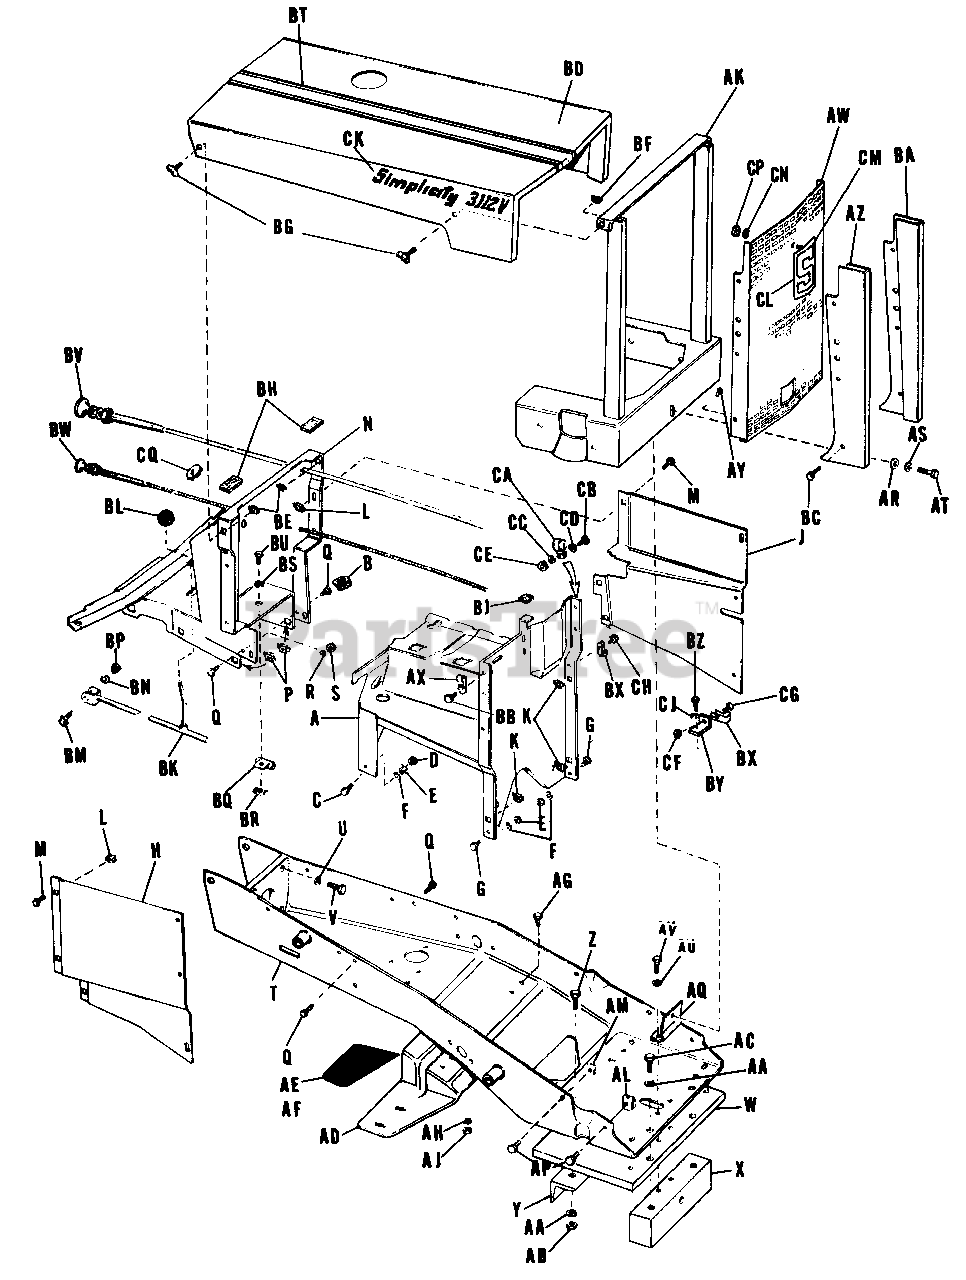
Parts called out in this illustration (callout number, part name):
A	Support Assembly, Fuel Tank & Battery
B	Steering Bushing
C	Hex. Cap Screw, 5/16"-18 x 1-1/4"
D	Full Lock Hex. Nut, 5/16"-18
E	Full Hex. Nut, 5/16"-18
F	Lock Washer, 5/16"
G	Hex. Cap Screw, 5/16"-18 x 5/8"
H	R.H. Side Panel
J	L.H. Side Panel
K	Nut Retainer
L	Nut Retainer
M	Hex. Cap Screw, 1/4"-20 x 5/8"
N	Inst. Panel Assembly
P	Nut Retainer (Frame Cover)
Q	Hex. Cap Serew, 1/4"-20 x 5/8"
R	Lock Washer, 1/4"
S	Full Hex. Nut, 1/4"-20
T	Frame Assembly
U	Lock Washer, 7/16"
V	Hex. Cap Screw, 7/16"-14 x 1-1/2"
W	Base Weight
X	Front Support, 1-3/4" x 2-1/2" x 8-5/8"
Y	Angle Assembly (Frame Rear)
Z	Hex. Cap Screw, 7/16"-14 x 1-1/2"
AA	Lock Washer, 7/16"
AB	Full Hex. Nut. 7/16"-14
AC	Hex. Cap Screw, 7/16"-20 x 1-1/2"
AD	Foot Rest
AE	L.H. Foot Rest Pad
AF	R.H. Foot Rest Pad
AG	Hex. Cap Screw 3/8"-16 x 3/4"
AH	Lock Washer, 3/8"
AJ	Full Hex. Nut 3/8"-16
AK	Cover & Tube Assembly
AL	Retainer Nut, (Front)
AM	Retainer Nut, (Rear)
AP	Hex Screw, Whiz-Lock Flange, 5/16-18 x 3/4
AQ	Bracket Assembly
AR	Plain Washer, 5/16"
AS	Lock Washer, 5/16"
AT	Hex. Cap Screw 5/16"-18 x 1-1/4"
AU	Lock Washer, 5/16"
AV	Hex. Cap Screw, 5/16"-18 x 1-1/2"
AY	Self Tapping Screw, #810 x 1/2"
AZ	R.H. Side Plate
BA	L.H. Side Plate
BB	Self Tapping Screw, #10-24 x 1/2"
BC	Self Tapping Screw #10 x 1/2"
BE	Nut Retainer (Rear)
BF	Nut Retainer (Front)
BG	Thumb Screw
BK	Shifter Rod Assembly
BM	Hex Cap Screw, 1/4"-20 x 5/8"
BN	Lock Washer, 1/4"
BP	Full Hex Nut 5/16"-18
BQ	Shift Rod Guide Assembly
BR	Retainer Nut
BS	Lock Washer 1/4"
BT	Hood Strip
BU	Hex Cap Screw, 1/4"-20 x 5/8"
BV	Throttle Control
BW	Choke Control
BX	Bowden Wire Clip
BY	Throttle Cable Bracket
BZ	Self Tapping Screw, 1/4"-20 x 5/8"
CB	Hex. Cap Screw, 1/4"-20 x 5/8"
CC	Lock Washer, 1/4"
CD	Plain Washer, 1/4"
CE	Full Hex. Nut, 1/4"-20
CF	Full Hex. Nut, #10-32
CG	Mach. Rd. Hd. Screw, #10-32 x 3/8"
CH	Self Tapping Rd. Hd. Screw, #10-24 x 1/2"
CJ	Lock Washer
CK	Simplicity & Number 3112 Film
CL	Plate, Assy.
CM	Emblem "S"
CN	Washer Lock
CP	Hex Nut #10-24
CQ	Plug Button
